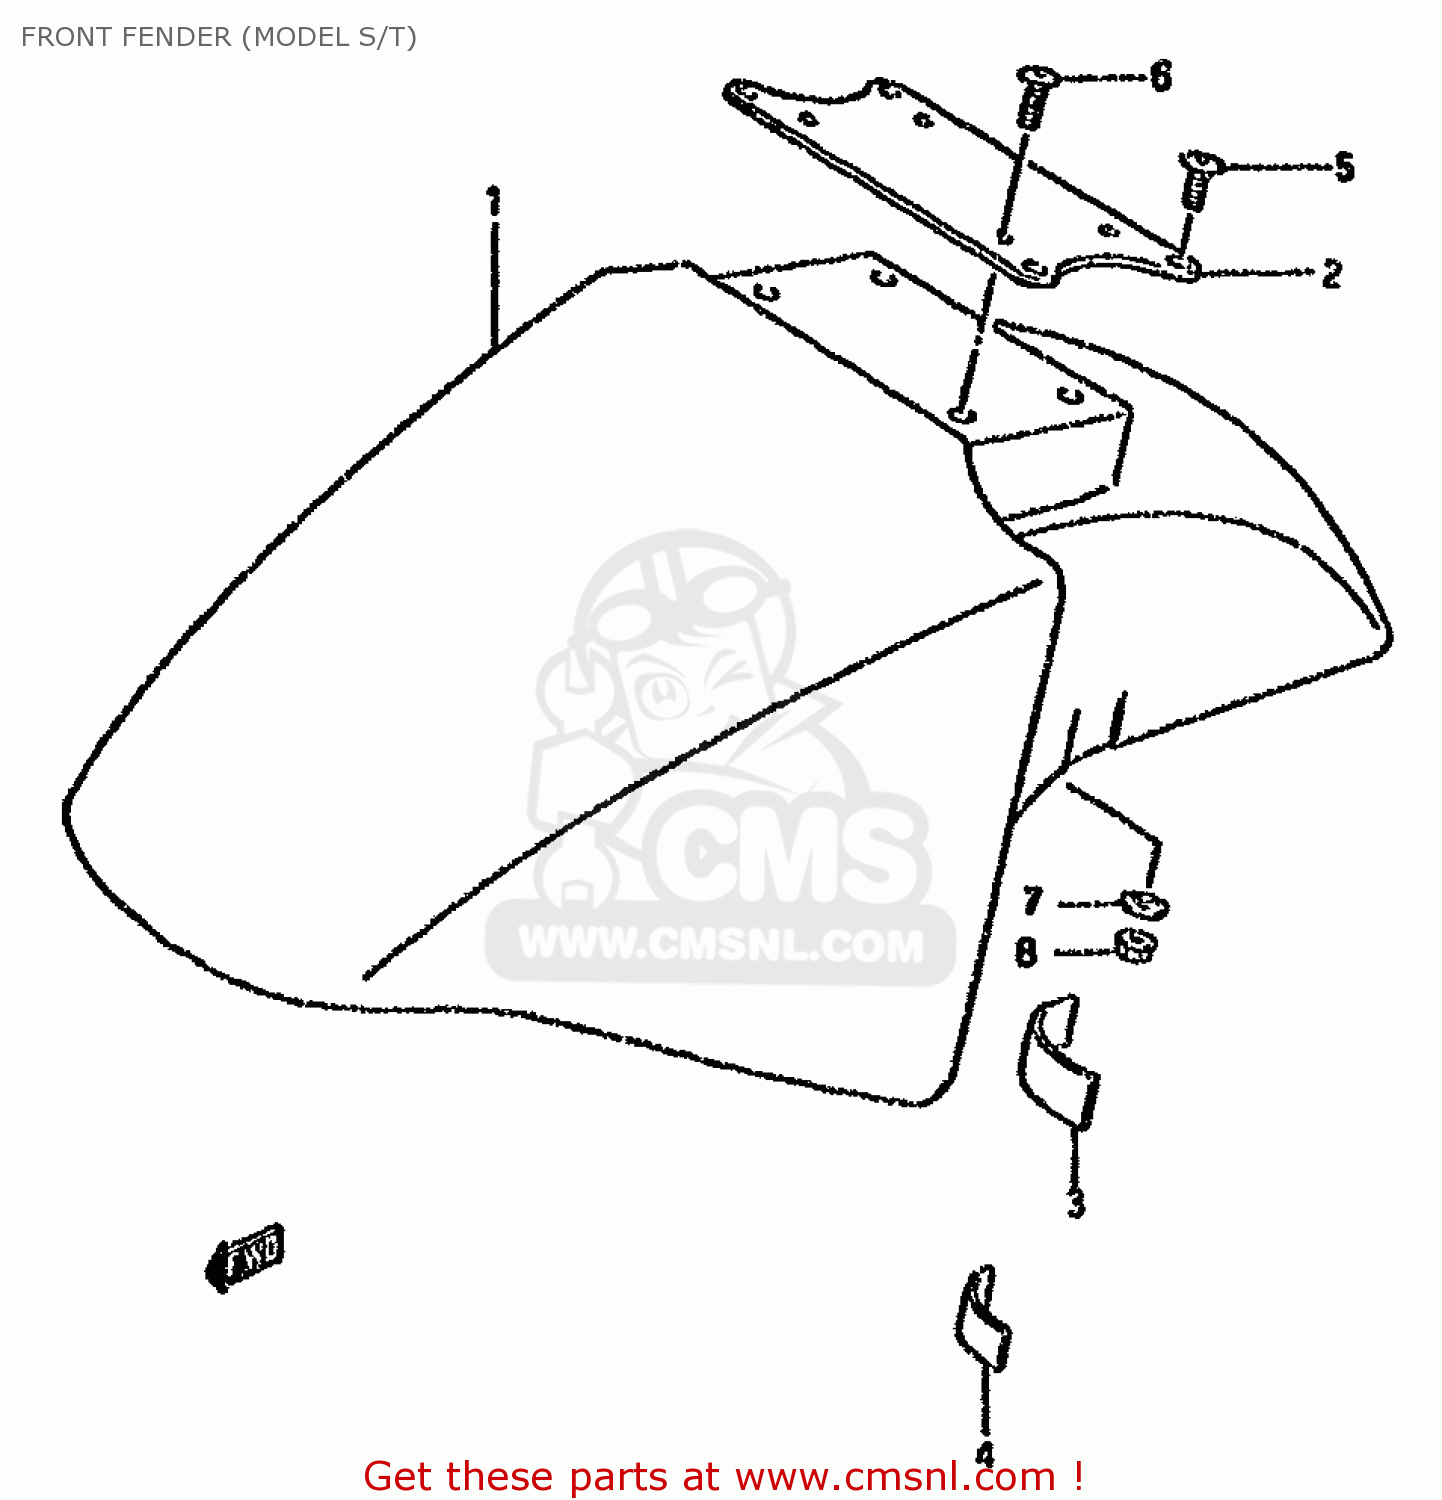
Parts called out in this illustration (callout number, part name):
1	FENDER,FR
2	BRACE,FR FENDER
3	CUSHION,FRONT FENDER
4	CUSHION
5	SCREW
6	NUT
7	WASHER
8	NUT
9	MUD FLAP, FRONT FENDER
10	SCREW
11	WASHER
12	NUT 5MM
13	PLUG(OD:10)
14	MUD FLAP SET,FRONT FENDER
